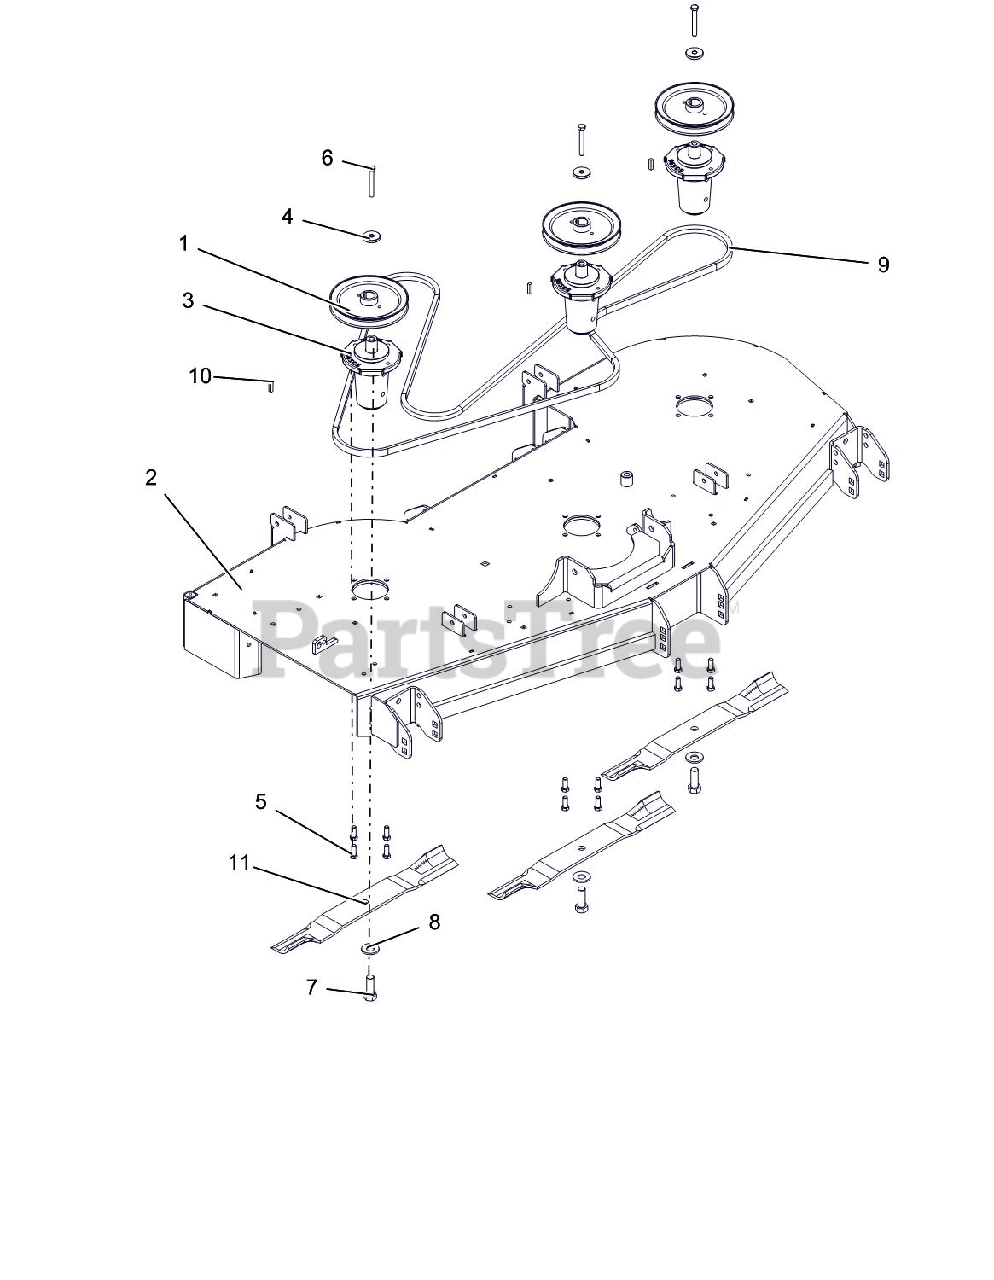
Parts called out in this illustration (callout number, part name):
1	PULLEY, 1.00 ID X 6.75 OD
2	KIT, 60" MOWER DECK W DECALS
3	ASM, MAINT FREE SPINDLE
4	RETAINER, SHEAVE
5	BLT-HEX .38-16X1.0 GR8 YZ EP30
6	BLT-HEX .38-16X2.75 GR8 YWZC
7	BLT-HEX .62-18X1.75 GR8 YWZC
8	WSHR-BLVL .669X1.535X.138
9	BELT, B-SECTION EPDM RAW EDGE
10	KEY, SQ .25X.25X1.00 RC 40-50
11	BLADE, MOWER (20.50")
